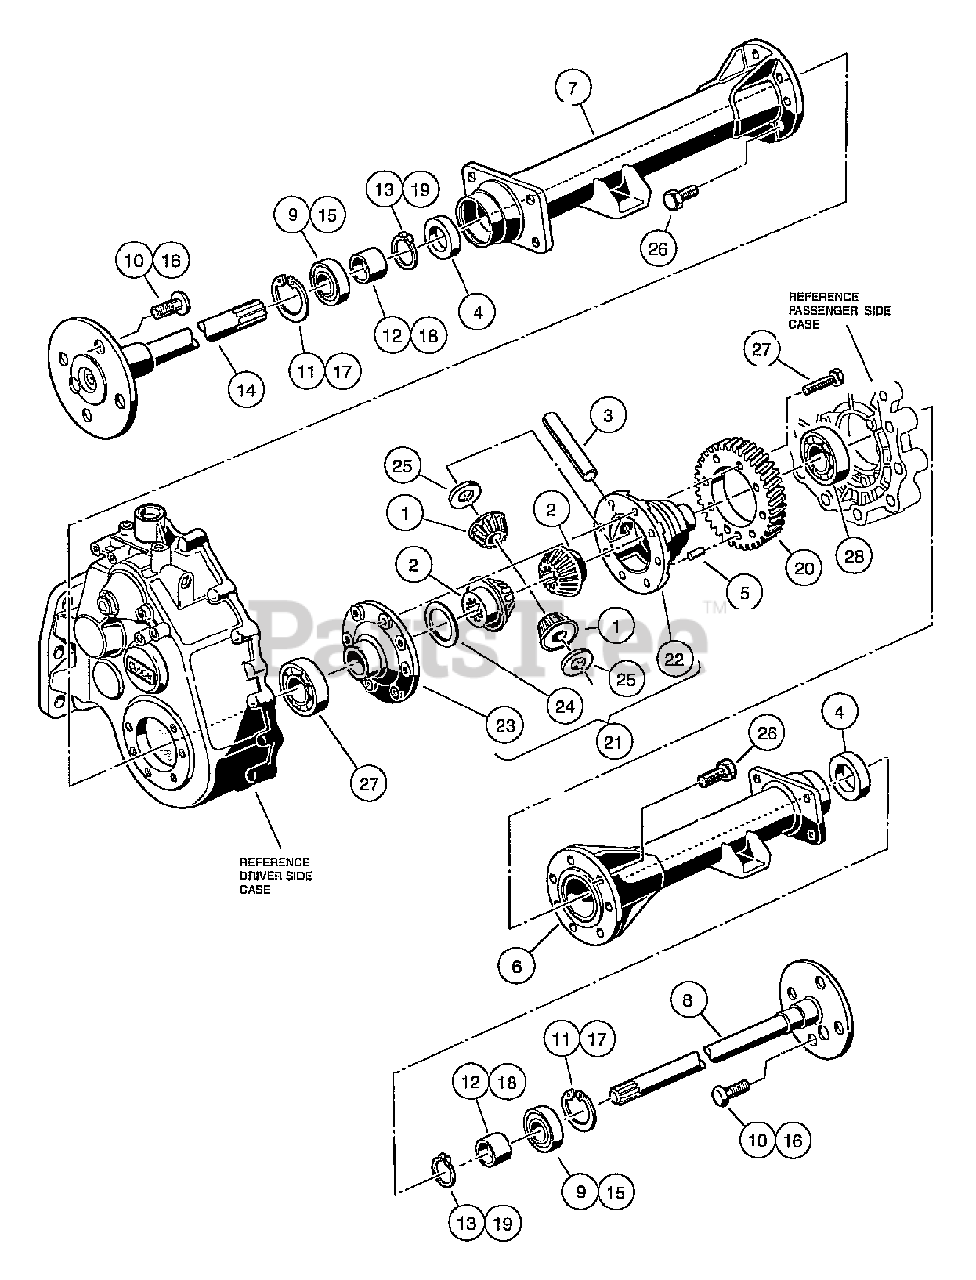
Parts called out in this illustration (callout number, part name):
1	Differential Idler Gear
2	Gear, Differential
3	Pin, Differential
4	Axle Shaft Oil Seal
6	Pipe
7	Pipe
8	Axle Assembly, Passenger Side
9	Outer Axle, Tube Bearing
11	Circlip Type C
12	Bushing
13	Retaining Ring
14	Axle Assembly, Driver-Side
15	Outer Axle, Tube Bearing
17	Clrclip Type C
18	Bushing
19	Retaining Ring
20	Gear, Helical
21	Kit, Differential Gear Case
22	Differential Gear Case, Left-Hand
23	Differential Gear Case, Right-Hand
24	Plate, Thrust (Differential Gear)
25	Plate, Thrust (Idler Gear)
26	Screw, M8-1.25 X 40mm Hex Head
27	Screw, M8-1.25 X 35mm Hex Head
28	Inner Axle, Tube Bearing
